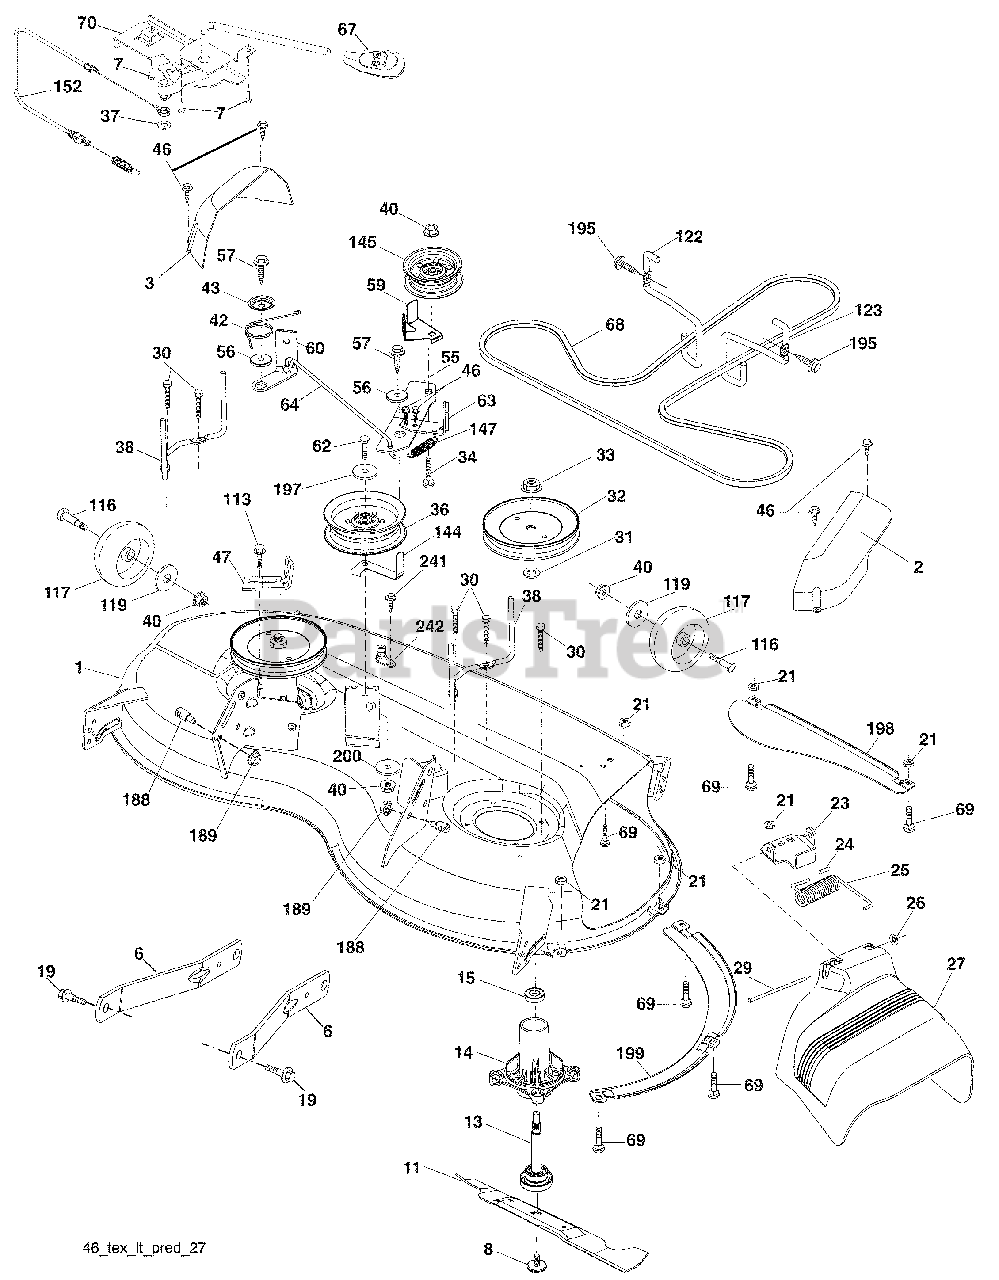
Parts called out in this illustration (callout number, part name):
1	Mower Housing
2	Cover Mandrel RH
3	Cover Mandrel LH
6	Arm Suspension
7	Screw #10 x 0.750
8	Bolt/Washer Asm 7/16-20 unf
11	Blade Mower
13	Shaft Assembly, Mandrel
14	Housing, Mandrel
15	Bearing, Ball, Mandrel
19	Bolt, Shoulder
21	Nut
23	Bracket, Deflector
24	Cap, Sleeve
25	Spring, Torsion, Deflector
27	Shield, Deflector
29	Rod, Hinge
30	Screw Thdrol Rolling Wsh Hd
31	Washer, Spacer
32	Pulley, Mandrel
33	Nut, Toplock, Flanged
34	Bolt Carr Sh. 3/8-16 x 1-1/2 Gr. 5
36	Pulley, Idler, Flat
37	Washer 13/32 x 13/16 x 16 Ga.
38	Keeper Belt LH Mandrel
40	Nut, Lock Flg. 3/8-16 unc
42	Spring Trosion Brake
43	Spring Torsion Retainer
47	Bracket Clutch Cable
55	Arm, Idler
56	Spacer, Retainer
57	Screw Hexwsh Thd 3/8-16 x 1
59	Guard, Tuv Idler (94)
60	Arm Brake Mower LH
62	Bolt 3/8-16 unc x 2-1/4 Gr. 5
63	Arm Brake Mower
64	Linkage Brake
67	Handle, Clutch Cable
68	V-Belt
69	Bolt
70	Clutch Asm. Cable
113	Screw 5/16-18
116	Bolt, Shoulder
117	Wheel, Gauge
119	Washer 13/32 x 1-1/4 x 12 Ga.
122	Keeper Belt Eng. LH
123	Keeper Belt Eng. RH
144	Keeper Belt
145	Pulley Idler
147	Spring Return
152	Cable Clutch Manual w/Spr.
188	Stud Fastener
189	Nut Lock Hex Flange
195	Screw 3/8-16 x 3/4
197	Washer 13/32 x 13/16 x 12 Ga.
198	Baffle Center Front
199	Baffle Front RH
200	Washer 13/32 x 1 x 1/2 11 Ga.
242	Washout Port
